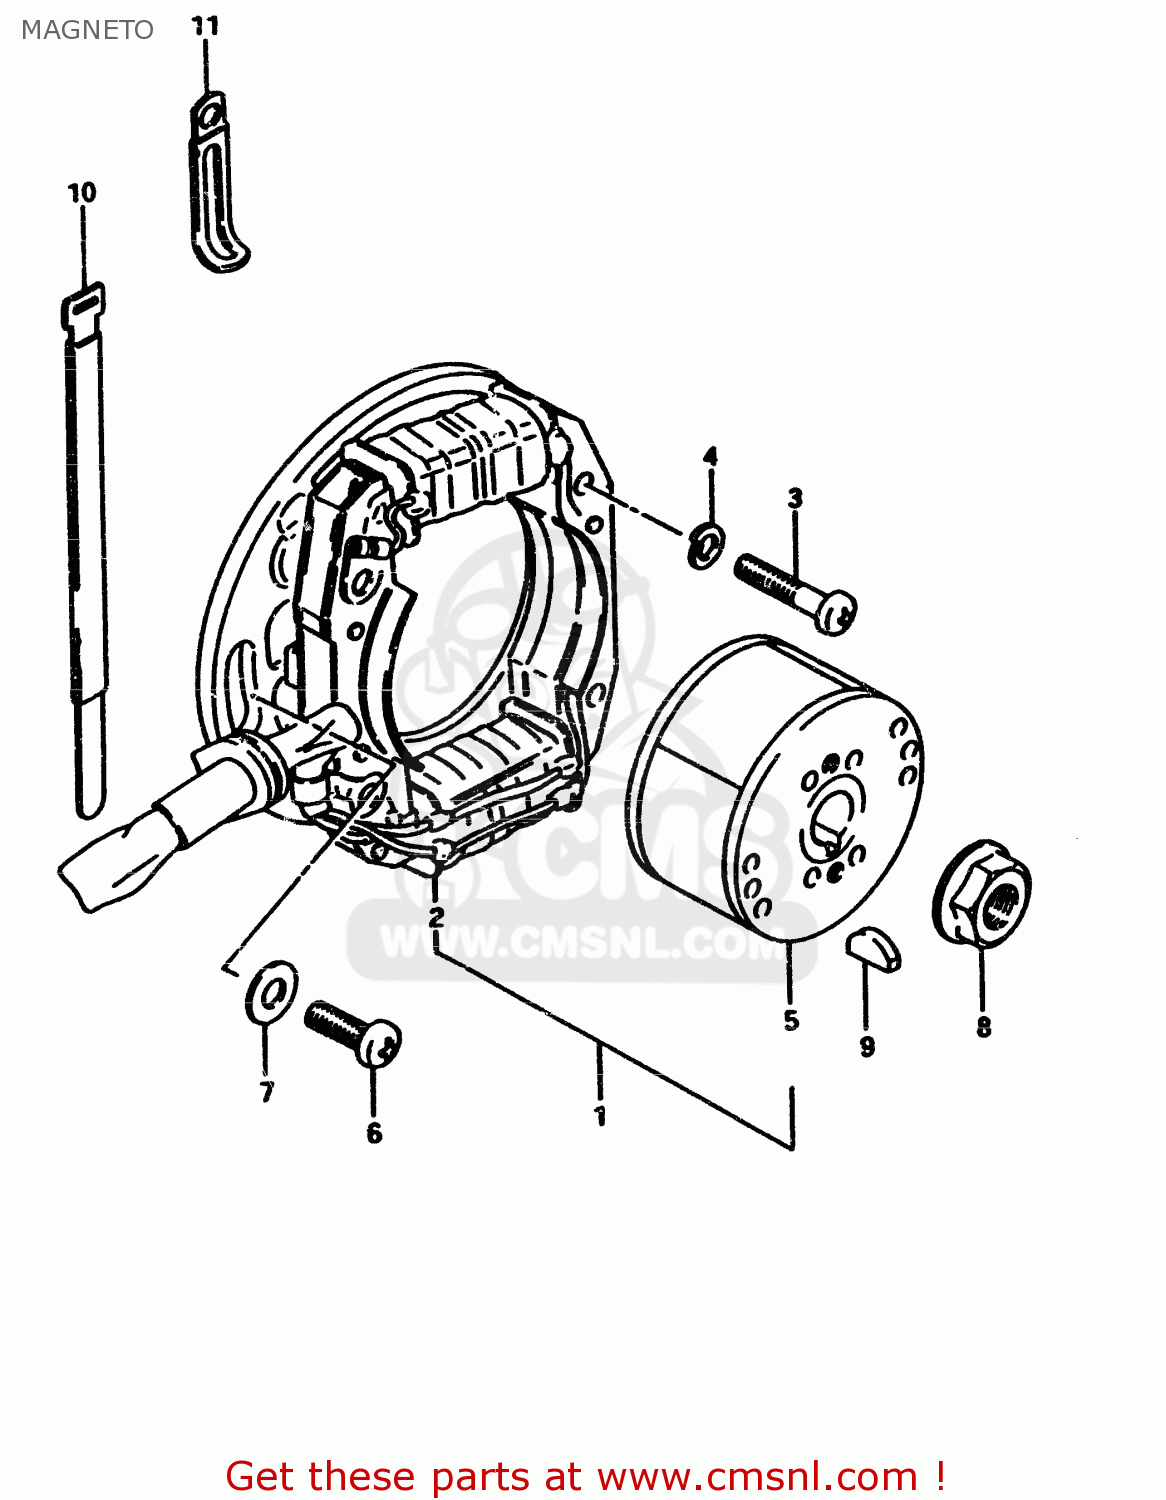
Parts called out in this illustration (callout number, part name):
1	MAGNETO ASSEMBLY
2	STATOR ASSEMBLY
3	SCREW 5X20
4	LOCK WASHER
5	ROTOR ASSEMBLY
6	SCREW
7	WASHER
8	NUT
9	KEY 4MM
10	CLAMP(L:250)
11	CLAMP L:35
